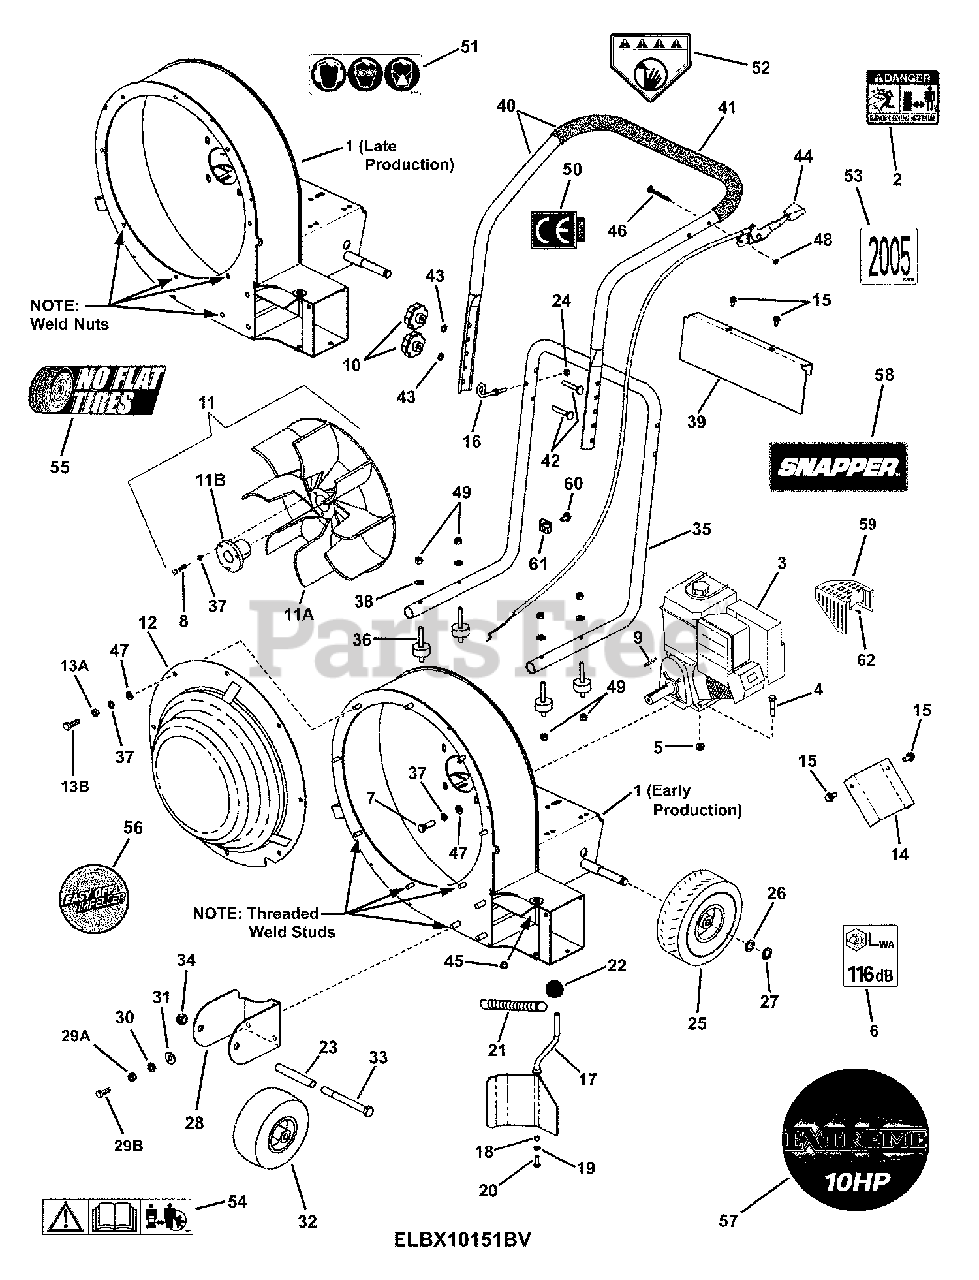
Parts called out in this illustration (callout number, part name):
1	WELDMENT, Housing- Extreme Blower
2	DECAL, Danger, Thrown Objects
3	* ENGINE, 10HP B&S Intek OHV
4	SCREW, 5/16-18 x 1-1/2" Hex Head Cap, GR 5
5	NUT, 5/16-18 Hex Flange Lock, GR 5
6	DECAL, Sound 116 dB
7	SCREW, 5/16-24 x 1-3/4" Hex Head Cap, GR 5
7	SCREW, 5/16-24 x 1" Hex Head Cap, GR 5
8	SCREW, 5/16-18 x 1-1/4" Hex Head Cap, GR 5
9	KEY, 1/4" Square x 1-7/16"
10	KNOB, 5/16-18 Fluted
11	ASSY, 15" 9 Blade Impeller
11A	IMPELLER, 15" O.D. Cast
11B	HUB, Taper-Lok, Type 1 - P1 x 1.125 (1.938 OAL)
12	WELDMENT, Intake Baffle- Extreme
13A	NUT, 5/16-18 Hex, GR 5 or B
13B	SCREW, 5/16-18 x 3/4" Hex Head Cap, GR 5
14	DEFLECTOR, Side Air
15	SCREW, 5/16-18 x 5/8" Hex Washer Self-Tap
16	ROPE GUIDE (1/4-20 thread)
17	** WELDMENT, Door Front/Side Discharge
18	BUSHING, Steel Sleeve .250 I.D. x .375 O.D. x .25 long
19	WASHER, .263 x .375 x .062 Split Lock
20	SCREW, 1/4-20 x 3/4" Hex Head Cap, GR 5
21	SPRING, Extension
22	KNOB, #230 Dimco (3/8-16 thread)
23	TUBE, Front Wheel- Extreme
24	NUT, 1/4-20 Hex Center Lock, GR 5 or B
25	ASSY., Wheel & Tire 410/350-4 "Flatfree"
26	WASHER, .64 x .99 x .05 Flat
27	RING, External Retaining
28	BRACKET, Front Wheel Mounting
29A	NUT, 3/8-16 Hex, GR 5 or B
29B	SCREW, 3/8-16 x 1" Hex Head Cap, GR 5
30	WASHER, 3/8" Split Lock
31	WASHER, 3/8" Flat
32	ASSY., Tire & Wheel 9 x 350-4 "Flatfree"
33	BOLT, 1/2-13 x 5" Hex Head Cap
34	NUT, 1/2-13 Hex Center Lock, GR 5
35	HANDLE, Lower Folding- Wide- Blower
36	MOUNT, Vibration (5/16-18 threads, both ends)
37	WASHER, 5/16" Split
38	WASHER, 5/16" Curved
39	DASH PANEL, Blower- Wide
40	ASSY., Upper Handle & Grip
41	GRIP, 1.0 x 21-1/2" Foam
42	BOLT, 5/16-18 x 2" Curved Head Square Neck, GR 2
43	WASHER, 5/16" Internal Tooth Lock
44	THROTTLE CONTROL, B&S, 35.00/1.62
45	BUSHING, Flanged .375 x .500 x .25 (.625 x .063 Flange)
46	SCREW, 1/4-20 x 2" Hex Head Cap, GR 5
47	WASHER, .34 x .69 x .08 Flat
48	NUT, 1/4-20 Hex Nyloc
49	NUT, 5/16-18 Hex Nyloc
50	DECAL, Euro Community (CE)
51	DECAL, Personal Protection
52	DECAL, Danger, Cut Finger (Euro)
53	DECAL, 2005 Year of Manufacture
54	DECAL, Caution, Symbols
55	DECAL, "No Flat Tires"
56	DECAL, Easy Off Impeller
57	DECAL, 10HP Extreme- Euro- Generic
58	DECAL, SNAPPER (Panel)
59	HEAT SHIELD, B&S 9 & 10 HP Intek
60	SCREW, Casing Clamp
61	CLAMP, Casing- Briggs Intek
62	SCREW, #8-18 Self-Tap
